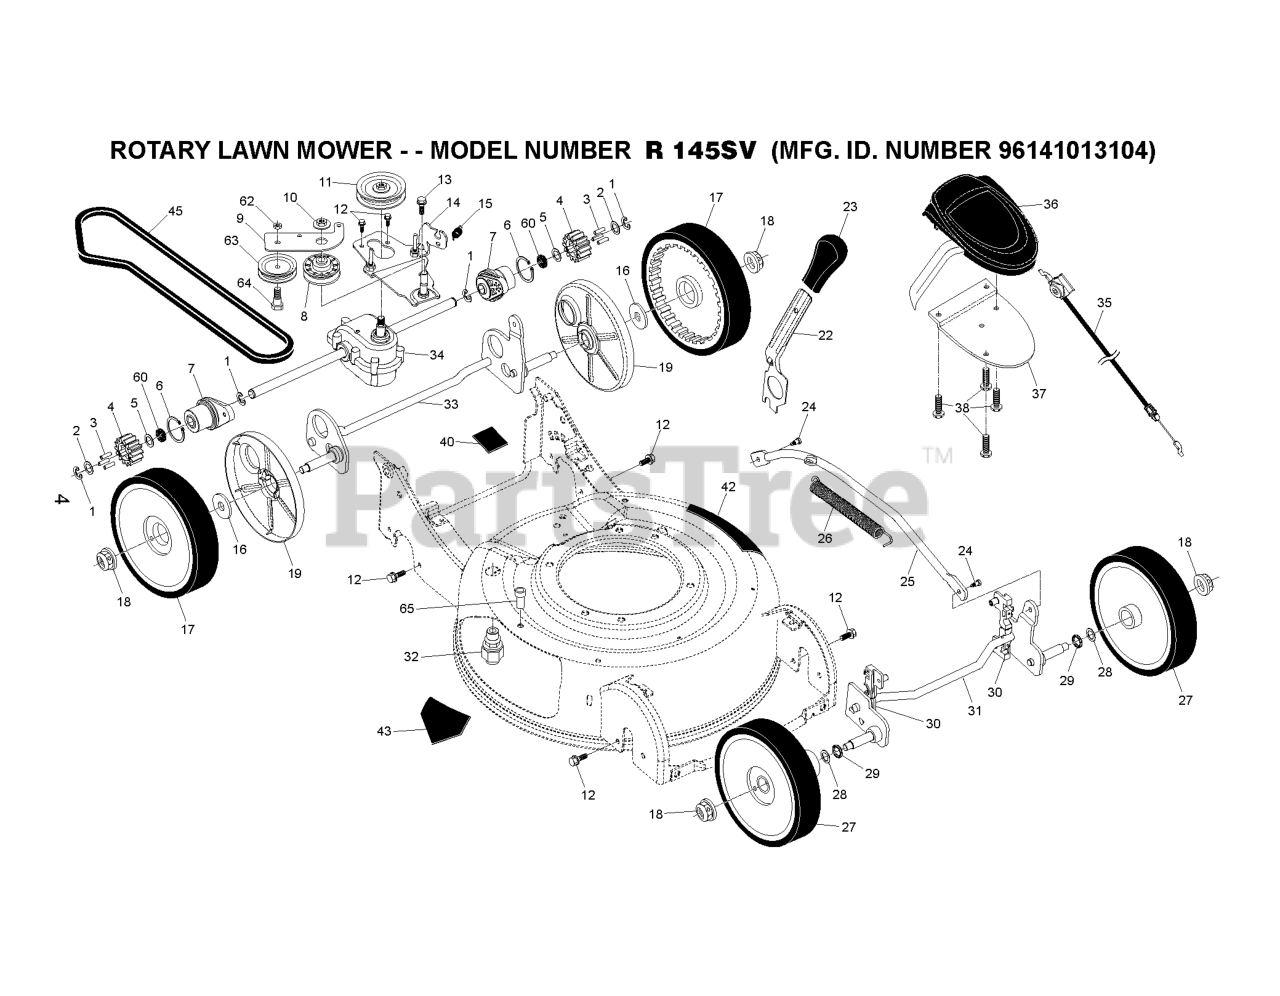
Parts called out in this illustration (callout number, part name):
1	E-RING 7/16 RE
2	THRUST WASHER
3	PAWL.DRIVE.ETCHED
4	PINION.DRIVE.WALK
6	RETAINING RING (2 2)(3 2)
7	BEARING.ASM
8	PULLEY.IDLER.V-BELT
9	ARM.IDLER.BZP
10	NUT.HEX.FLANGE.3/8-16.LOCKNUT
11	PULLEY.1.PIECE
13	SCREW 14-20 X 5/8
15	SPRING.RETURN
16	WASHER FLUT
17	WHEEL.8X1.75.H3SPK.RAD3.GY.BU3
18	NUT.HEX.FLANGE.3/8-16.LO(3 2)
19	COVER.DUST.WHEEL
24	SHOULDER BOLT SEMI GIMLET PT.
25	ROD.LIFT.BZP
26	SPRING EXTENSION
27	WHEEL & TIRES ASSY, FRONT
28	WASHER.FLAT.1/2
29	O-RING..070X.487.NEOPRENE
30	BUSHING.FRONT.TORQUE.SHAFT
37	BRACKET.DRIVE.CONTROL.MOUNT.BL
38	SCREW, PHILLIPS HEAD 10 X 5/8
43	DECAL.INTERNATIONL.CUTFINGER
62	NUT.CENTERLOCK.5/16-
63	IDLER PULLEY
64	SHOULDER BOLT
